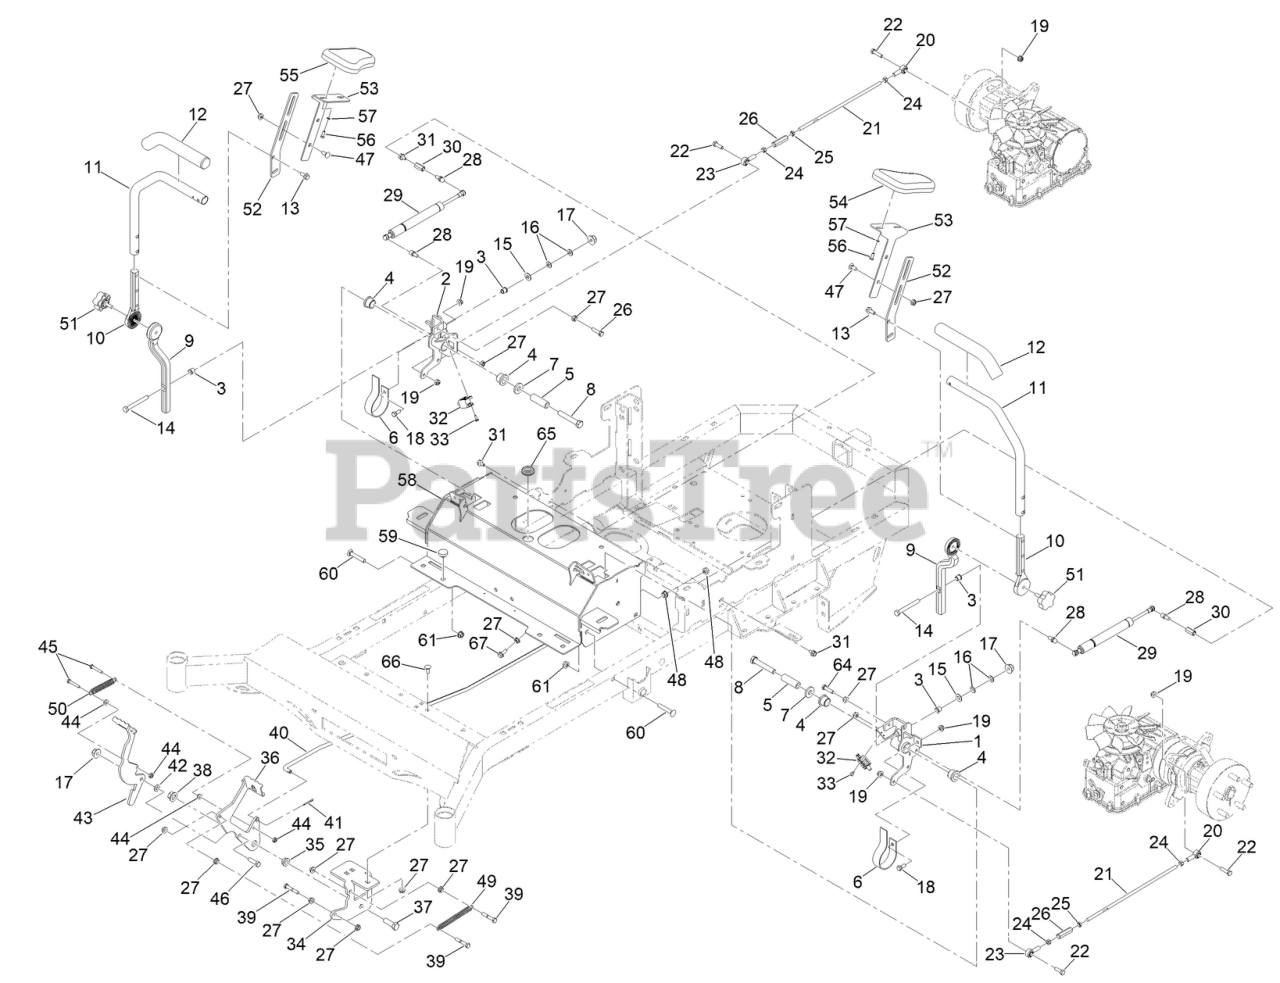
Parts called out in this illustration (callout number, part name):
1	LH PIVOT ASM
2	RH PIVOT ASM
3	BUSHING-FLANGE
4	BUSHING-FLANGE
5	SLEEVE-PIVOT
6	SPRING-LEAF
7	1/2 FENDER WASHER 1-1/4IN OD ZINC
8	1/2-13 X 3 HEX C/S GR 5 ZINC W/LOCTITE
9	ADJUSTABLE LWR DRIVE ARM
10	ADJUSTABLE UPP DRIVE ARM
11	MOWER DRIVE HANDLE TUBE ABC
12	CONTROL ARM HANDLE GRIP
13	SCREW-HHF
14	SCREW-HH
15	WASHER-FLAT
16	WASHER-BELLEVILLE
17	3/8-16 NYLON INSERT FLANGE L/NUT YZ
18	SCREW-HH
19	NUT-HF, NI
20	5/16-24 SPHER ROD END ZINC RH THD FEM
21	TRANS DRIVE ARM LINKAGE STANDARD TRANS
22	SCREW-HH
23	ROD END-BALL JOINT
25	NUT-JAM
26	NUT-SLEEVE
28	5/16-18X1.286 DAMPER BALL STUD (.562 TL)
29	CONTROL ARM DAMPER
30	STANDOFF-HEX
31	SCREW-HHF
32	NO PLUNGER LIMIT SWITCH
33	8-32 X 1/2 IND. HWH SLOT TYPE F TCS ZINC
34	MWR FRAME BRAKE MTG BRKT PAINT
35	1/2IN ID X 3/4IN OD X 3/8IN FLANGE BUSH
36	MWR BRAKE LOCK LEVER ASSY PAINTED
37	SCREW-HH
38	NUT-LOCK
40	MWR BRAKE LINKAGE
41	PIN-COTTER
42	3/8 ID X 3/4 OD X .125 THK BRONZE WASHER
43	MWR BRAKE UNLOCK LEVER ASSY PAINTED
44	1/4-20 HEX FLANGE NUT
45	1/4-20 X 1-1/4 HEX C/S GR 2 ZINC
46	SCREW-HH
47	BOLT-CARR
48	3/8-16 HEX FLANGE NUT W/SERR ZINC YELLOW
49	2020 MWR BRAKE PEDAL TENSION SPRING
50	MWR BRAKE PEDAL RELEASE SPRING
51	5/16-18 X 1 SL 5-LOBE MALE ST KNOB 1.90
52	MWR ARM PAD TUBE MTG BRKT PAINTED
53	MWR ARM PAD MTG BRKT PAINTED
54	2020 MWR DRIVE ARM SUPPORT PAD LT
55	2020 MWR DRIVE ARM SUPPORT PAD RT
56	SCREW-HSBH
57	1/4 EXT TOOTH LOCKWASHER ZINC
58	ASM, GT-TRAC [GRAY]
59	PUSH-IN RUBBER BUMPER MWR FLOOR
60	SCREW-CARR
64	SCREW-HH
65	GROMMET-RUBBER
66	BOLT-CARR
67	5/16-18 X 3/4 HEX FLANGE BOLT GR 8 YZ
